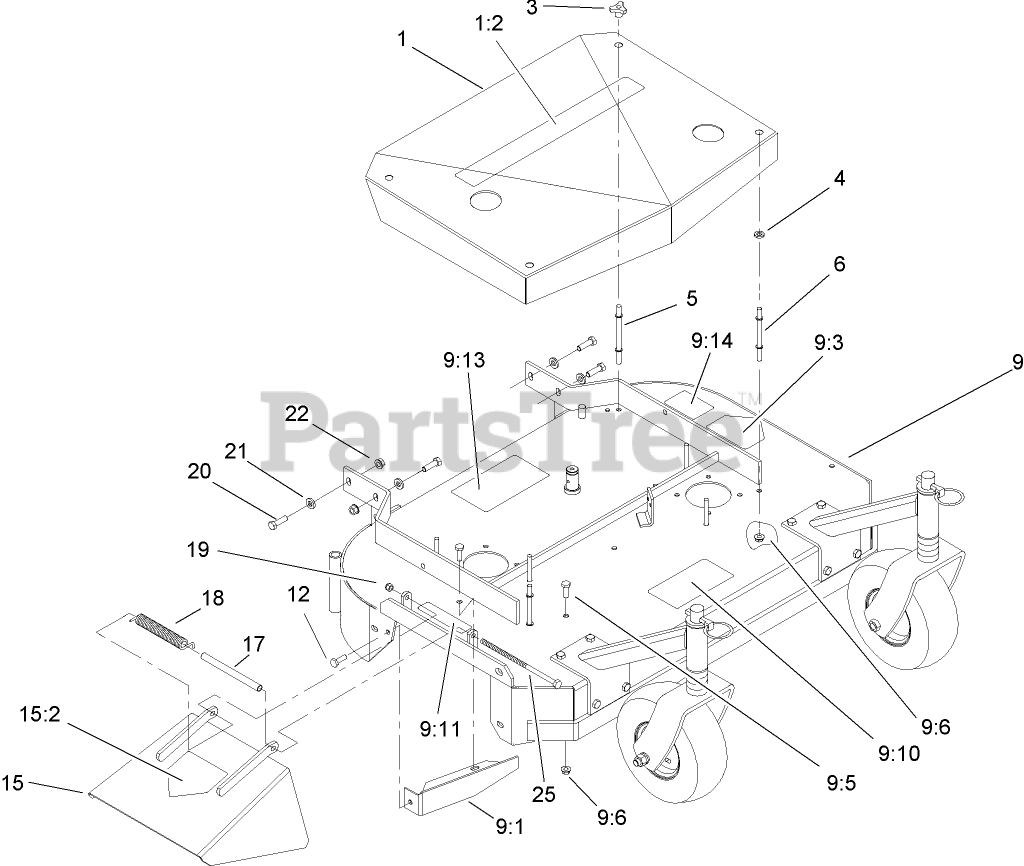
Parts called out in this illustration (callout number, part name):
1	SHIELD-BELT
3	KNOB-HANDLE
4	WASHER
5	STUD-SHIELD, BELT (LONG)
6	STUD-SHIELD, BELT (SHORT)
9	DECK ASM
9:1	BAFFLE-DOGLEG
9:3	DECAL-DANGER
9:5	SCREW-HH
9:6	NUT-HF
9:10	DECAL-DANGER, THROWN OBJECT
9:11	DECAL-DANGER
9:13	DECAL-ROUTING, BELT
9:14	DECAL-TORQUE, BOLT
12	SCREW-HH
15	CHUTE-DISCHARGE
15:2	DECAL-DANGER
17	SPACER-SPRING
18	SPRING-DEFLECTOR
19	NUT-LOCK, NI
20	SCREW-HH
21	WASHER-BELLEVILLE
22	NUT-HHF, WHIZ
25	SCREW-HH
